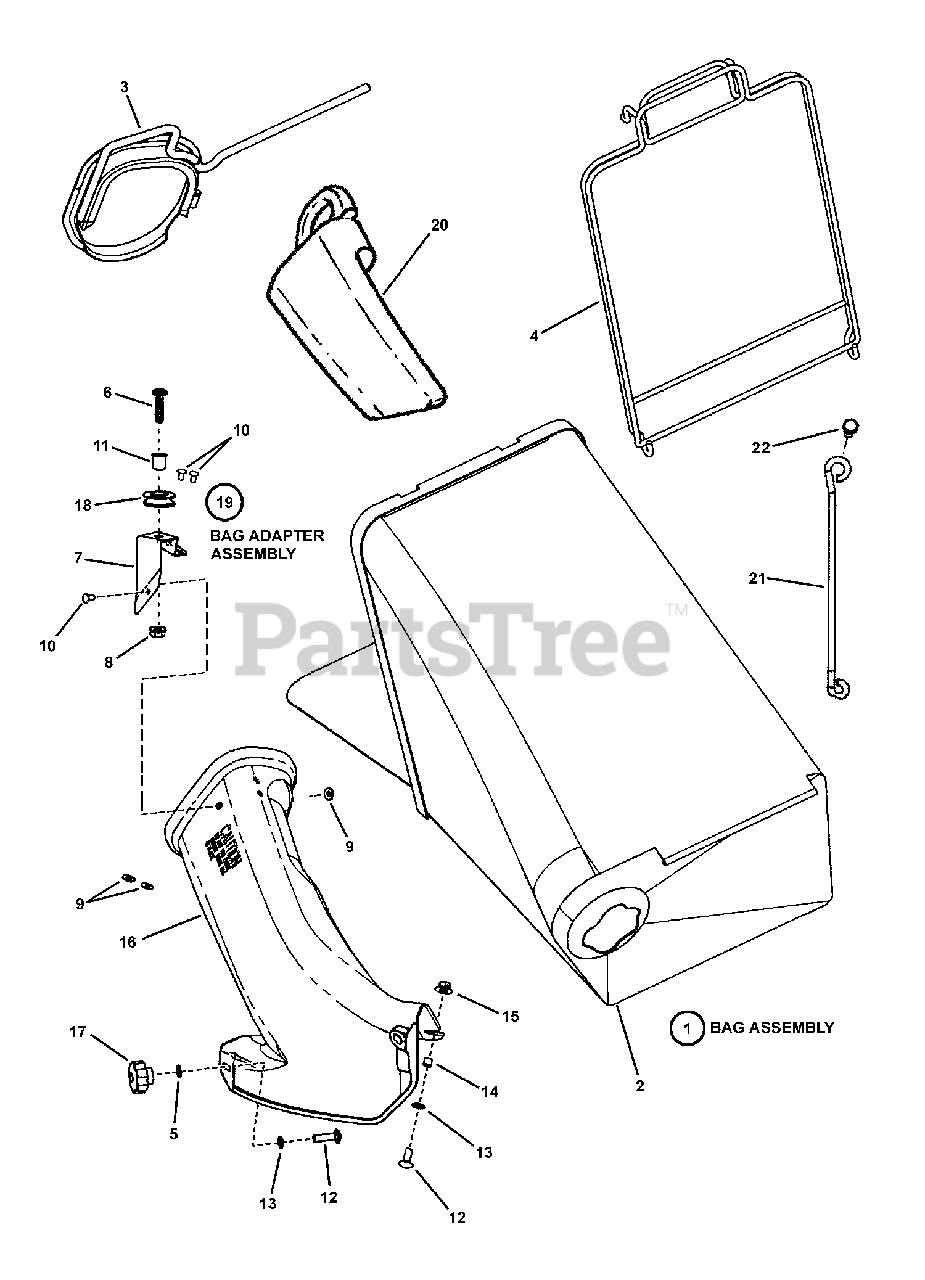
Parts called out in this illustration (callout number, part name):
1	GRASS BAG ASSY. (Door) No Graphics
2	GRASS BAG, (Door) No Graphics
3	CONNECTOR, Grass Bag (weldment)
4	ASSEMBLY, Bag Wire (12" Wide)
5	WASHER, 5/16" Internal/External Tooth Lock
6	SCREW, 5/16-18 x 1-1/4" Pan Head Machine
7	BRACKET, Rope Guide
8	NUT, 5/16-18 Hex Flange Lock, GR 5
9	WASHER, 15/32" Flat
10	RIVET, 3/16 x .344
11	BUSHING, Flange, .381 x .625 x .62
12	BOLT, 5/16-18 x 3/4" Short Neck Carriage GR 5
13	RETAINER, 5/16" Bolt
14	SPACER, .316 I.D. x .375 O.D. x .310 thick
15	NUT, 5/16-18 Hex Large Flange Center Lock
16	ADAPTER, Grass Bag
17	KNOB, Fluted, 5/16-18 x 1/2"
18	PULLEY, Nylon
19	ASSY, Grass Bag Adapter
20	PLUG, Chute Adapter
21	BRACE, Bag Adapter, Kawasaki
22	SCREW, M6 x 1.0 x 30MM Hex Head Cap
